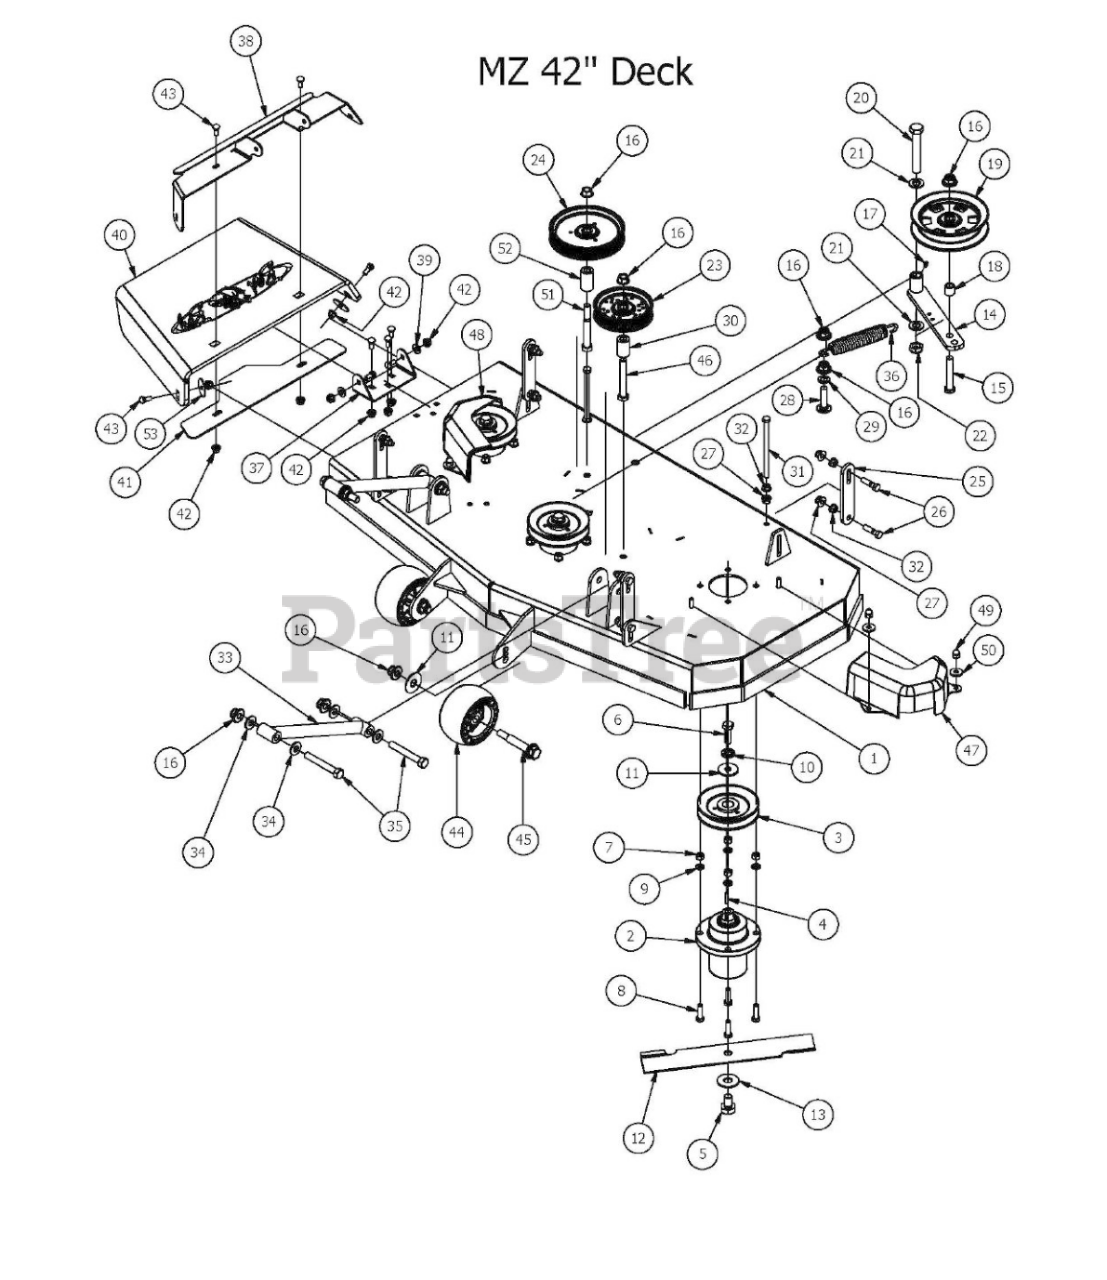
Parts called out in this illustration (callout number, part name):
1	2017 42" MZ Deck-Welded Shell
3	MZ Deck Pulley
4	3/16 x 1 Square Key
5	5/8" x 1 1/2" Grade 8 Hex Bolt (Fine)
6	1/2"-20 x 1 1/2 - Grade 5 Fine Thread Bolt
7	3/8" Hex Nut
8	3/8" x 1 1/4" Hex Bolt
9	3/8" Lock Washer
10	1/2" Lock Washer Zinc
11	1/2" Belleville Washer
12	MZ 42 Blade
13	5/8" Flat Washer
14	Deck Idler
15	1/2-13 x GR 5 Hex Bolt Zinc
16	1/2-13 Nylon Insert Flange Nut
17	1/4" Press in Grease Fitting
18	Spacer 3/4 OD x 1/2 ID x 3\4 Length
19	5" Idler Pully
20	5/8" x 4" Hex Bolt
21	.630 ID Plastic Washer
22	5/8-11 Nylon Insert Jam Half Nut
23	4 3/4 Idler Pulley - ABFI-76
24	5-3/4 Idler Pulley-Capitol Stampings
25	2017 MZ/ZT Deck Hanger
26	3/8" x 1 1/2" Hex Bolt
27	3/8 Nylock Flange Nut
28	1/2 x 2" Carriage Bolt
29	.517 Square Hole Round Washer
30	Idler Pulley Standoff
31	3/8-16 x 5 1/2 Hex Bolt
32	3/8" Flange Nut
33	MZ/ZT Deck Locator
34	.505 Nylon Spacer
35	1/2-13 x 3 1/2 GR 5 Hex Bolt
36	2015 Deck Idler Spring
37	Chute Hanger 48 MZ
38	Discharge Chute Bracket 48 MZ (Upper)
39	.360 ID Plastic Washer
40	Rubber Discharge Chute MZ (Component)
41	2017 MZ Discharge Chute Bracket-Lower
42	5/16" Nylon Flange Nut
43	5/16-18x3/4 carriage bolt
44	Deck Wheel
45	Deck Wheel Bolt
46	1/2 x 3 1/2 Flange Bolt Grade 8
47	pulley cover non-chute side
48	pulley cover chute side
49	Acorn nut-pulley Cover
50	.360 ID Plastic Washer-Black
51	1/2" x 4" Bolt (Grade 8)
52	1 3/4" Pulley Spacer
53	5/16" Fender Washer
